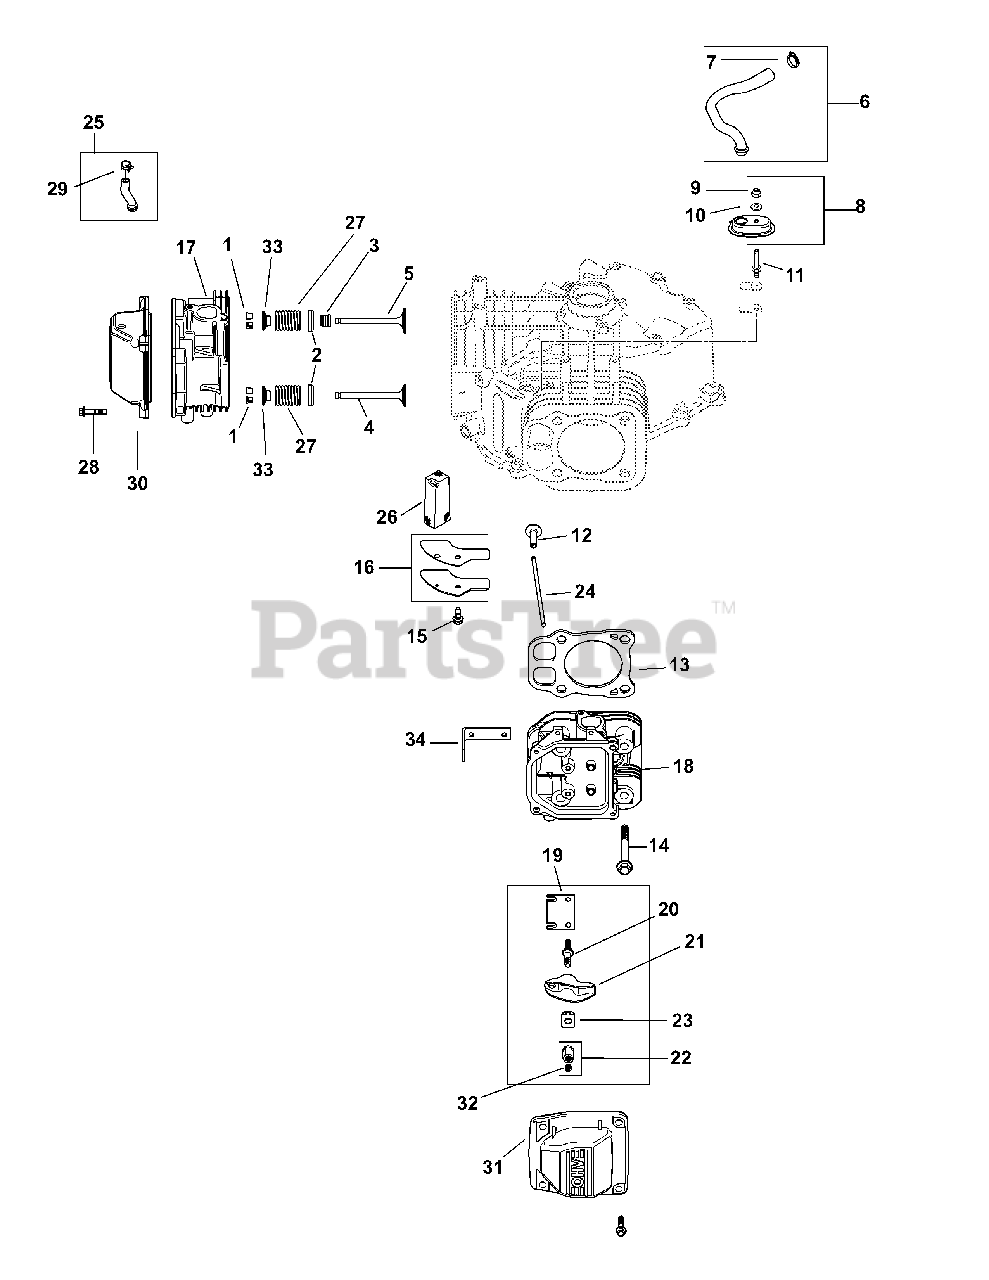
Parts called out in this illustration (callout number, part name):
1	Retainer Kit
2	Spring Retainer
3	Valve Stem Seal
4	Exhaust Valve (STD)
5	Intake Valve (STD)
6	Breather Hose Kit (Inc. #7)
7	Hose Clamp, 1/2
8	Housing Breather Kit (Inc. #9 & 10)
9	Lock Nut, M5 x 8
10	Sealing Washer
11	Breather Cover Stud
13	Cylinder Head Gasket Kit
14	Flange Screw, M10 x 1.5 x 90
15	Flange Screw, M6 x 1.0 x 16
16	Breather Cover
17	Cylinder Head Assembly Kit, #1
18	Cylinder Head Assembly Kit, #2
22	Hex Nut Assembly (Inc. #32)
23	Rocker Arm Pivot
25	Fuel Pump Hose Kit (Inc. #29)
26	Breather Filter
27	Valve Spring
28	Pan Head Screw
30	Rocker Cover
33	Valve Spring Cap
34	Lifting Strap
